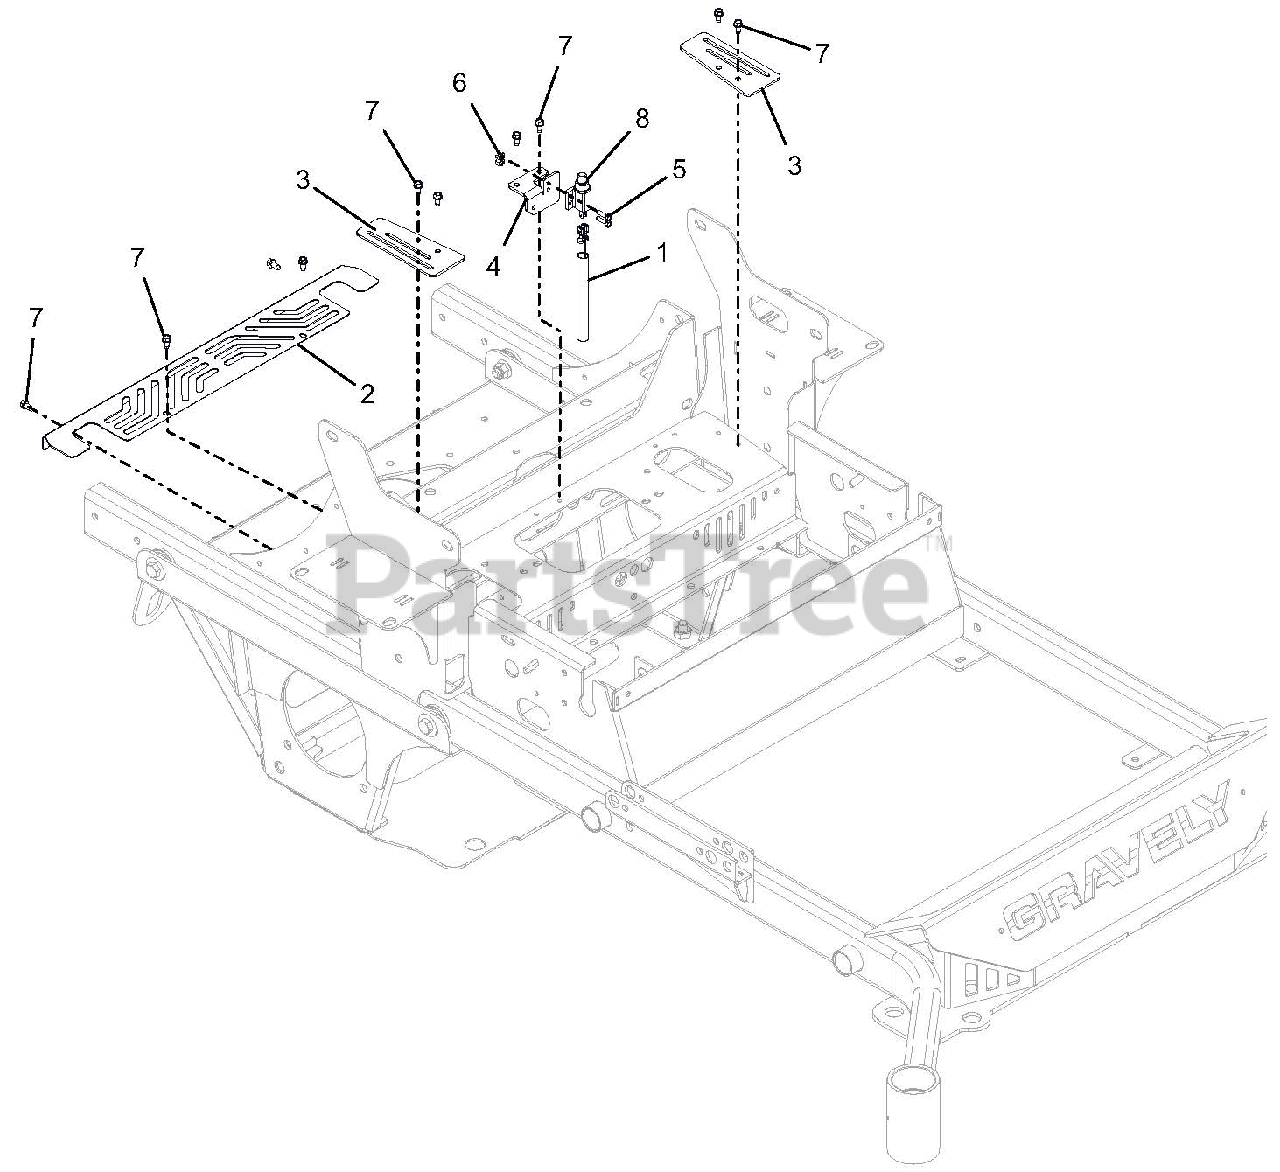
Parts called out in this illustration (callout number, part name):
1	HARNESS, CE SEAT SWITCH
2	GUARD, CE REAR ACCESS
3	GUARD, SEAT PLATE FINGER
4	BRKT, SEAT SWITCH MOUNT 272CE
5	@SCR-MCH 10-24X.75 HWH YWZC
6	@NUT-LK-NYL 10-24 W/INSRT YWZC
7	SCR-TAP .25-20X.50 HWH TR YWZ
8	SWITCH-SINGLE POLE N.O.W/COVER
